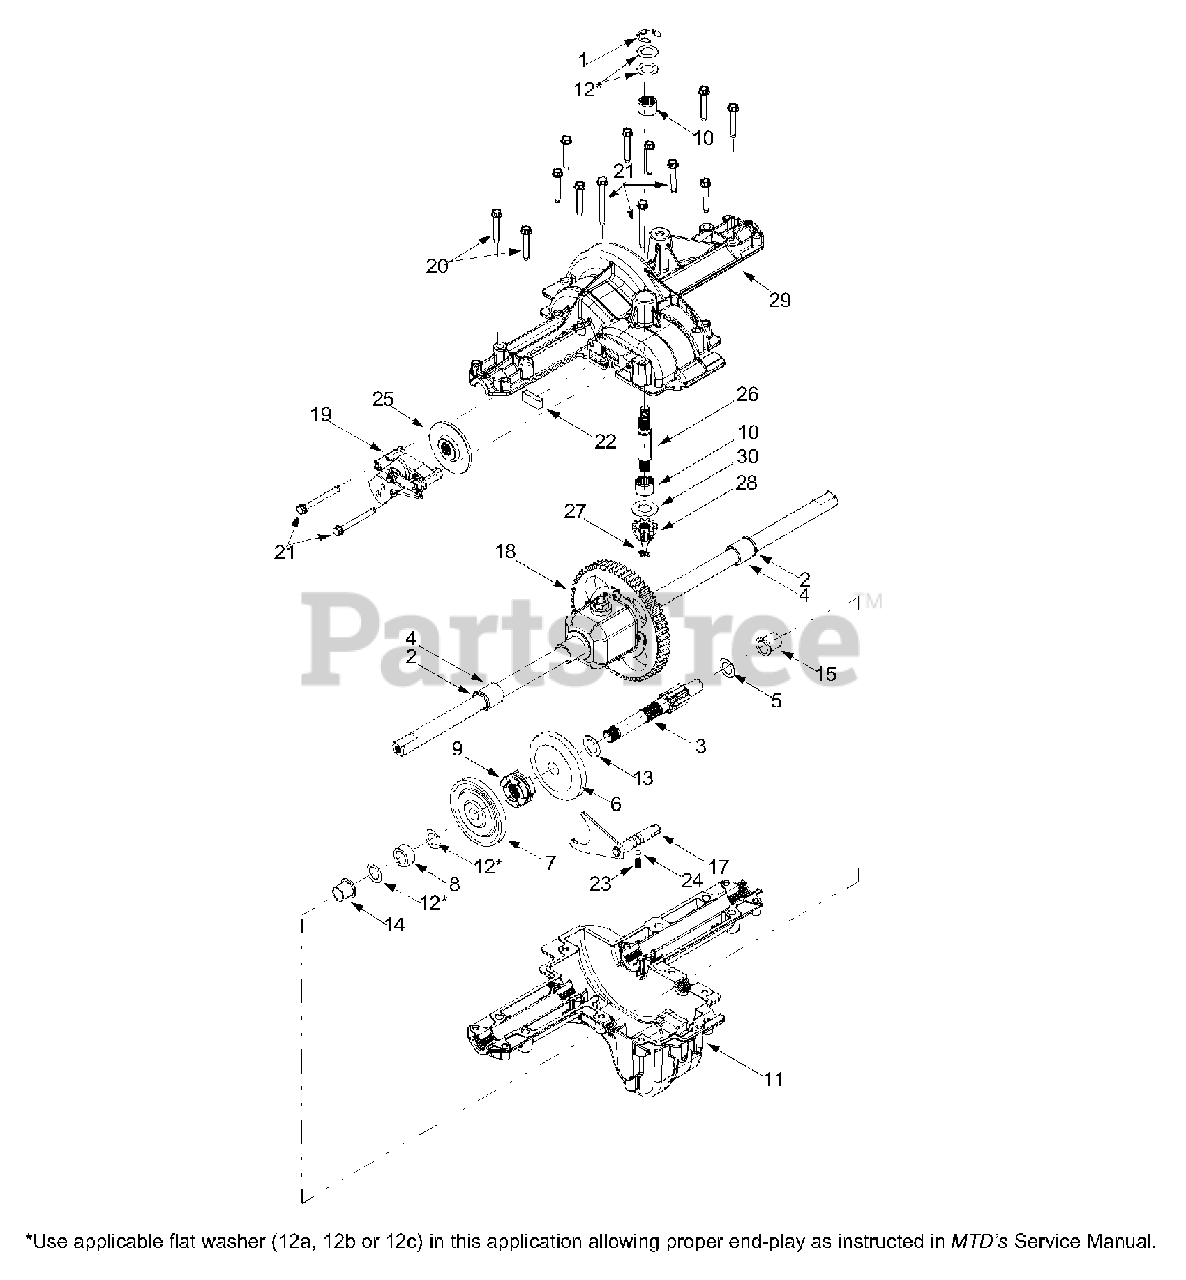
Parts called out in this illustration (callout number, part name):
1	E-Ring, .75
2	Seal, .75 x 1.0 x .125
3	Drive Shaft
4	Sleeve Bearing, .75 x .1.0 x 1.0
5	Thrust Washer, 1.0 x .632 x .0
6	42-Tooth Bevel Gear
7	42-Tooth Bevel Gear
8	Spacer, .633 x 1.0 x .513
9	Clutch Collar
10	Needle Bearing, .625 x .875
11	Lower Housing
13	Flat Washer, .70 x 1.125 x .031
14	Flange Bearing, 5/8 x 3/4 x 3/4
15	Flange Bearing, 5/8 x 3/4 x 15/16
17	Detent Shaft Assembly
18	Differential Assembly
19	Brake Assembly
20	Self-tapping Screw, 1/4-20 x 1.625
21	Self-tapping Screw, 1/4-20 x 2.375
22	Brake Pad
23	Compression Spring
24	Detent Ball
25	Brake Disc
26	Input Shaft
27	Retaining Ring, .437
28	14-Tooth Bevel Pinion
29	Upper Housing
30	Thrust Washer, .635 x 1.25 x .042
